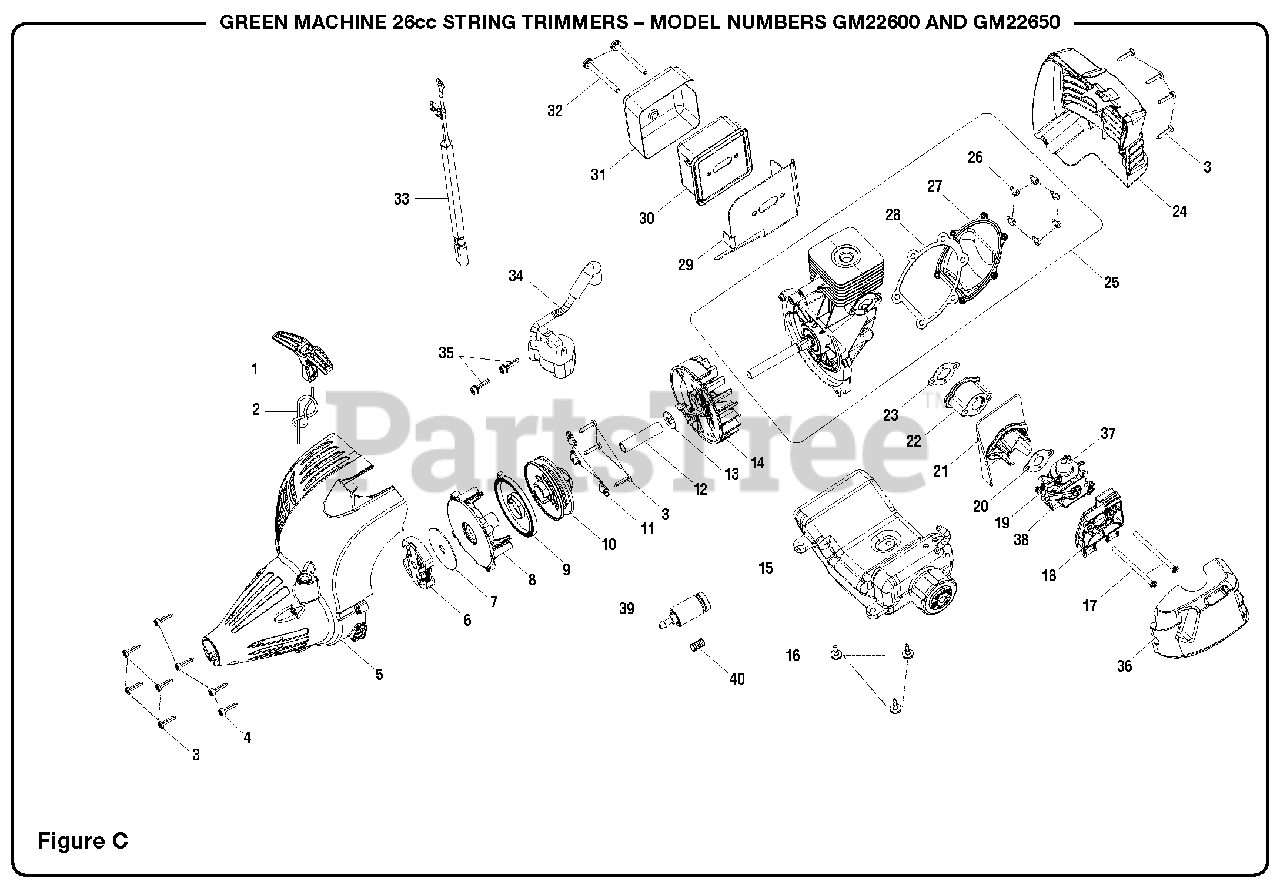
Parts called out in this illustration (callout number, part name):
1	Starter Grip
2	Starter Rope (42 in)
3	Screw (M4 x 18 mm)
4	Screw (M4 x 16 mm)
5	Starter Housing Assembly
6	Clutch Assembly
8	Starter Baffle
9	Spring and Container
10	Easy Starter Assembly
11	Pulley Retainer
12	Spacer Tube
13	Washer
14	Flywheel Assembly
15	Fuel Tank and Cap Assembly
16	Screw (M4)
17	Bolt (M5 x 70 mm)
18	Air Box Base
19	Carburetor Assembly
20	Outer Heat Dam Gasket
21	Air Baffle
23	Inner Heat Dam Gasket
24	Rear Housing
25	Short Block Assembly
26	Screw (M4 x 12 mm)
27	Crankcase Cover
28	Crankcase Cover Gasket
29	Muffler Gasket
30	Muffler Assembly
31	Muffler Housing
32	Muffler Bolt (10-24 x 2-1/8 in)
33	Electrical Lead Wire Assembly
34	Ignition Module
35	Screw (M4 x 19 mm)
36	Air Box Cover
37	Primer Bulb (Ruixing)
38	Choke Lever (Ruixing)
39	Fuel Filter
40	Compression Spring
